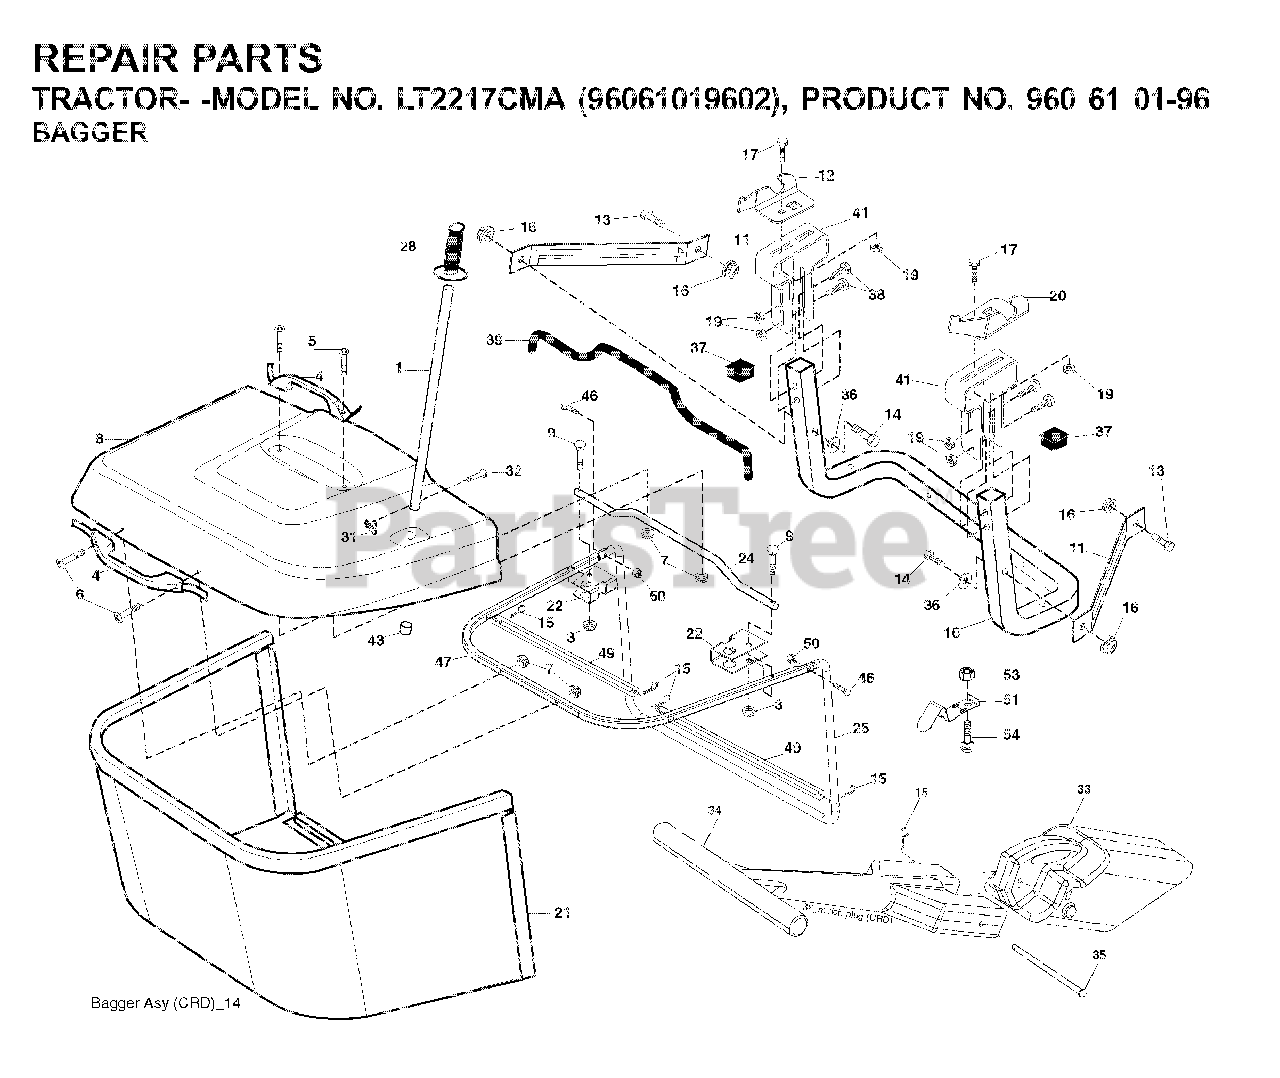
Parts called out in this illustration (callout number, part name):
1	TUBE HANDLE
3	NUT T
5	SCREW.PAN.HEAD
11	BRACKET
14	BOLT-HEX EAK
15	RETAINER-SPRNG RB
16	NUT LOCK FLG 3/8-16 UNC
17	BOLT
19	NUT LOCK HEX FLANGE 5/16-18
20	BRKT.PIVOT.RH.CRD
21	BAGGER.ASM.CRD.2007
22	BRACKET
24	TUBE
28	GRIP.HANDLE.BLACK
31	RETAINER CLIP
32	RIVET,DRILLED
33	PLUG
35	PIN
38	BOLT.5/16-18X2.5
41	BRKT, BAGGER
43	PLUG, TUBING END
46	BOLT.CARRIAGE.5/16-18
50	NUT.71038.31-18.HEX.NYLOCK
53	NUT
54	BOLT
